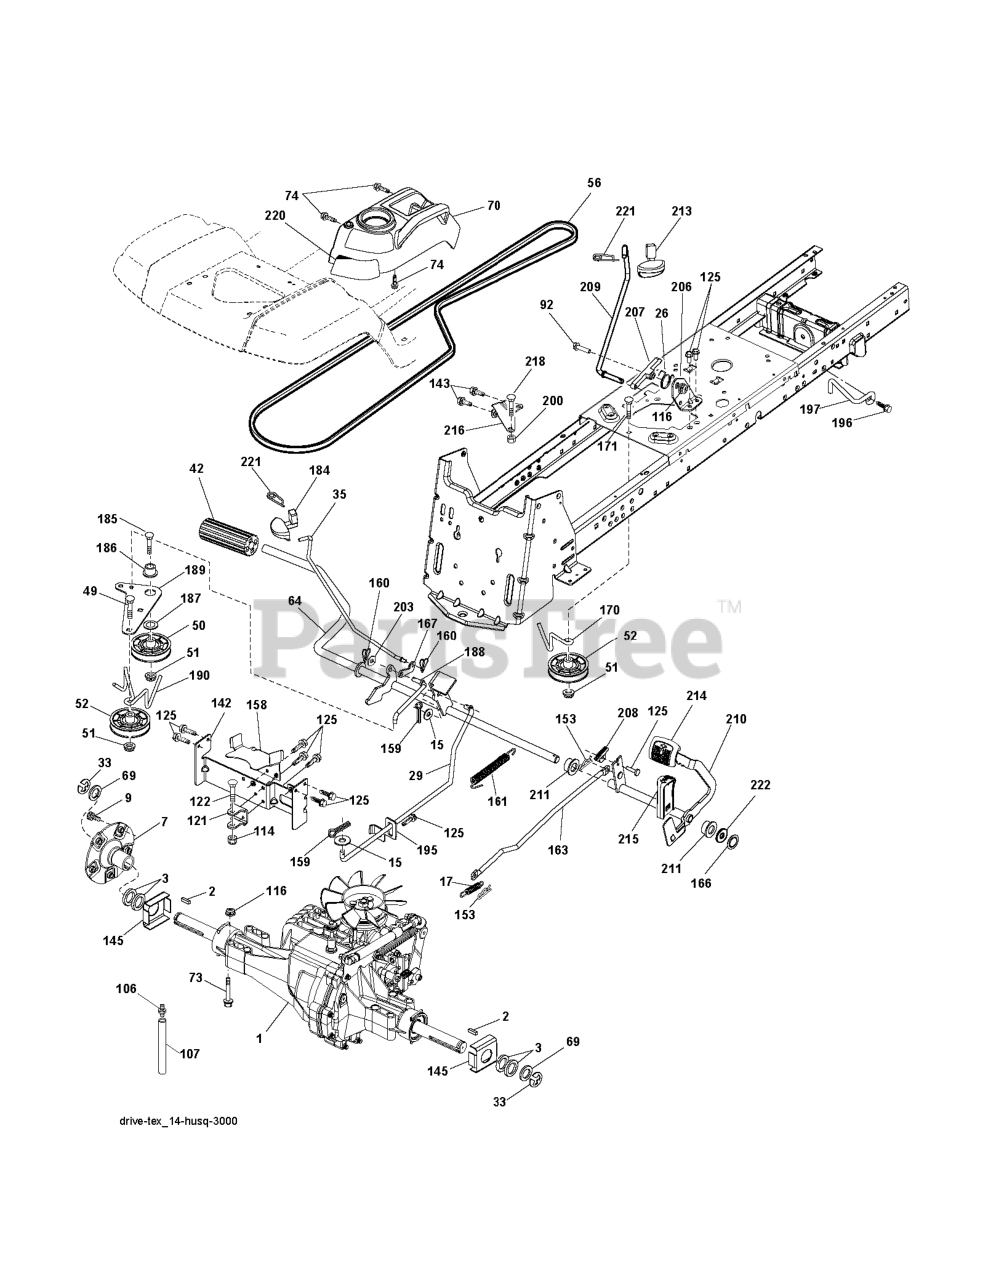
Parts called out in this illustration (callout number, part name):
2	KEY 1/4 X 2.5
7	HUB.ASM.WHEEL.REAR.23"TEX
15	WASHER
17	SPRING.BRAKE.HG3000/3500
26	SPRING.RETURN.CRUISE
29	ROD.BRAKE.HG3000/3500
33	E RING HYT
35	ROD.BRAKE.PARKING.GT.H
42	COVER, PEDAL (1 2)
50	IDLER.FLAT.910.OFFSET
51	NUT LOCK FLG 3/8-16 UNC
52	IDLER.V-GROOVE.910.OFFSET
56	BELT.V.GROUND.DRIVE
64	SHAFT.ASM.PEDAL.BRK.CNTR
70	RP CONSOLE.ASM.PCH.W/TB
73	BOLT HEX FLGHD 5/16-18X3 GR. 5
74	SCREW.HI-LO.CONSOLE
92	BOLT
106	CAP, VENT ASSY
114	NUT.71038.31-18.HEX.NYLOCK
116	NUT LOCK HEX FLANGE 5/16-18
121	BRACKET STRAP TORQUE
122	BOLT.5/16-18X2.5
125	SCREW
142	STRAP.TORQUE.HG3000/K46
143	Screw 5/16-18 x 1/2 Hex, Self Tapping 5/16-18 x 1/2
145	WASHER.AXLE.FLANGE.HG-3000
153	RETAINER M
158	KEEPER BELT
159	COTTER PIN
160	RETAINER CLIP
161	SPRING.RETURN.CLUTCH.2006
166	NUT.PUSH.625.2006
167	LATCH.BRAKE.SPRING
170	KEEPER.V-IDLER.CENTER.
184	HANDLE.PARKG.BRK.HUSQ X667
186	SPACER.RETAINER
187	WASHER 12/32X2X10GA
188	RP.LINK.CLUTCH.GROUND.DRIVE
189	BELLCRANK.GROUND.DRIVE.TEX.
190	KEEPER.BELLCRANK.DRIVE
195	RETAINER.ROD.BRAKE.HG3000.TEX
196	SCREW 3/8-16X1
197	BRKT.ANIT-ROTATION.CLUTCH
200	NUT.CENTERLOCK.5/16-
203	WASHER
206	BRKT.MOUNT.LATCH.CRUIS
207	LATCH.CONTROL.CRUISE
208	GEAR.SECTOR.CONTROL.CR
209	ROD.CONTROL.CRUISE.GT.
210	ROCKER.ASM.PEDAL.CONTR
211	BEARING.NYLON
213	KNOB.CONTROL.CRUSIE.HU
214	PEDAL.FORWARD.TEX.GT.4
215	PEDAL.REVERSE.TEX.GT.4
216	BRACKET.PULLEY.IDLER.W/TEX
218	BOLT.5/16-18X1-1/4 FULL.THREAD
220	REFLECTOR.RH.TEX GT
221	RETAINER.SPRING.CLIP.H
222	WASHER
